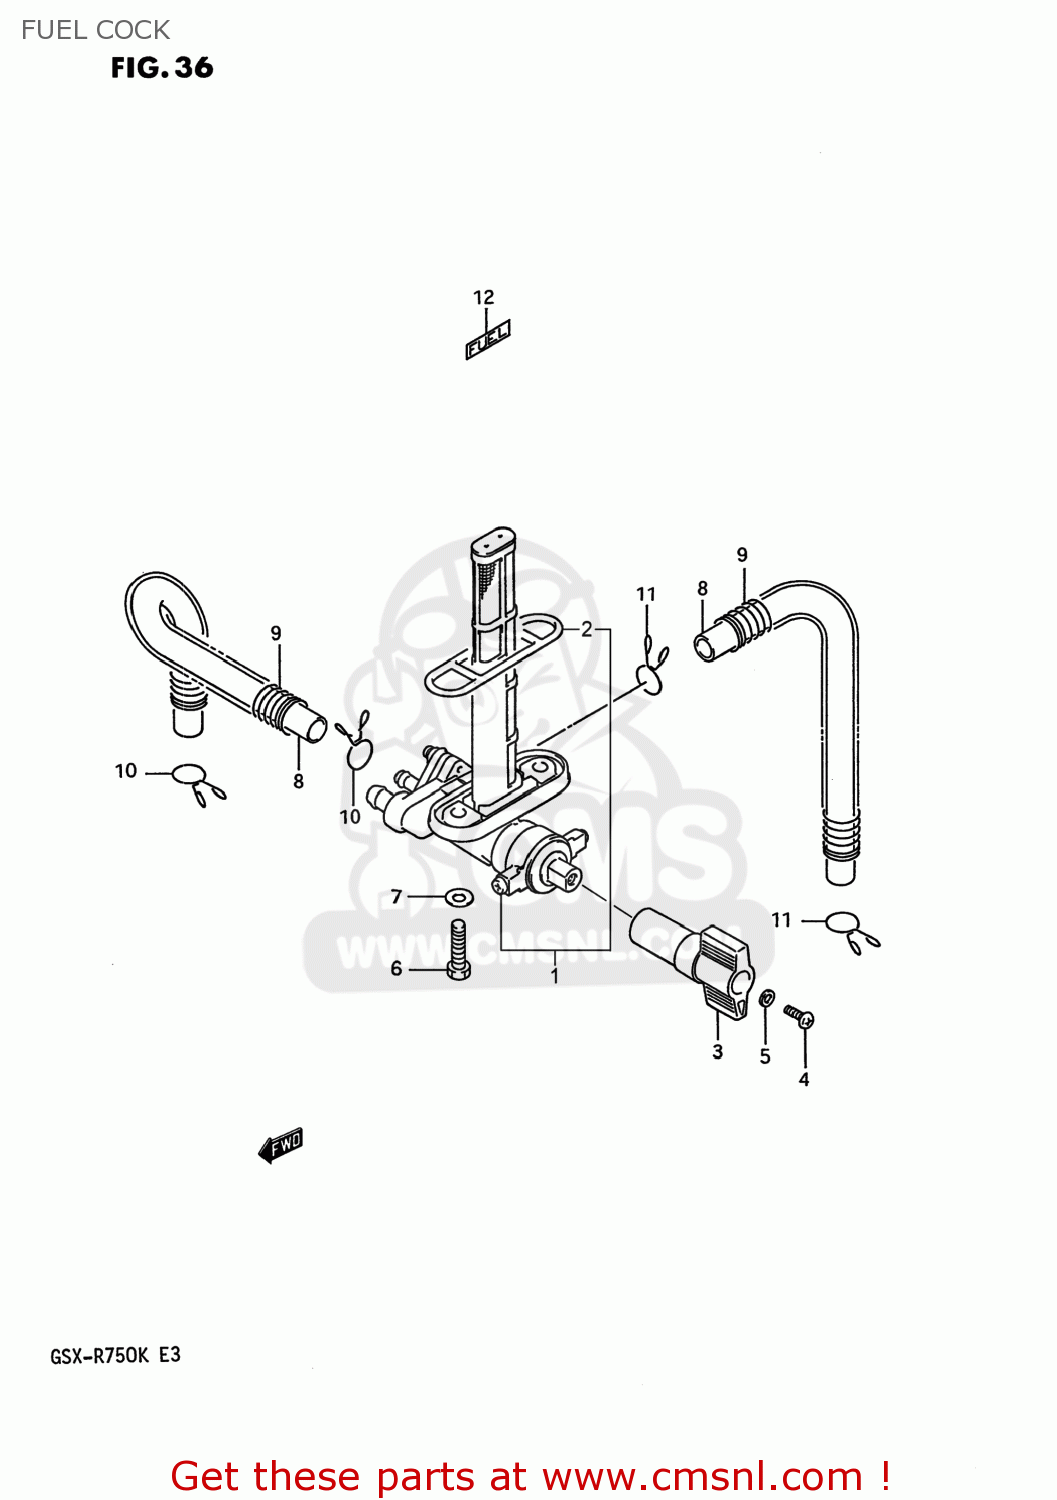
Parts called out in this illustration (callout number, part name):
1	COCK ASSEMBLY,FUEL
2	O RING,FUEL TANK JOINT
3	LEVER,FUEL COCK
4	SCREW
5	LOCK WASHER
6	BOLT(6X20)
7	GASKET(6.4X11.5X0.8) (NAS)
8	HOSE(7X10.2X600)
9	SPRING
10	CLIP
11	CLIP
12	LABEL (FUEL)
